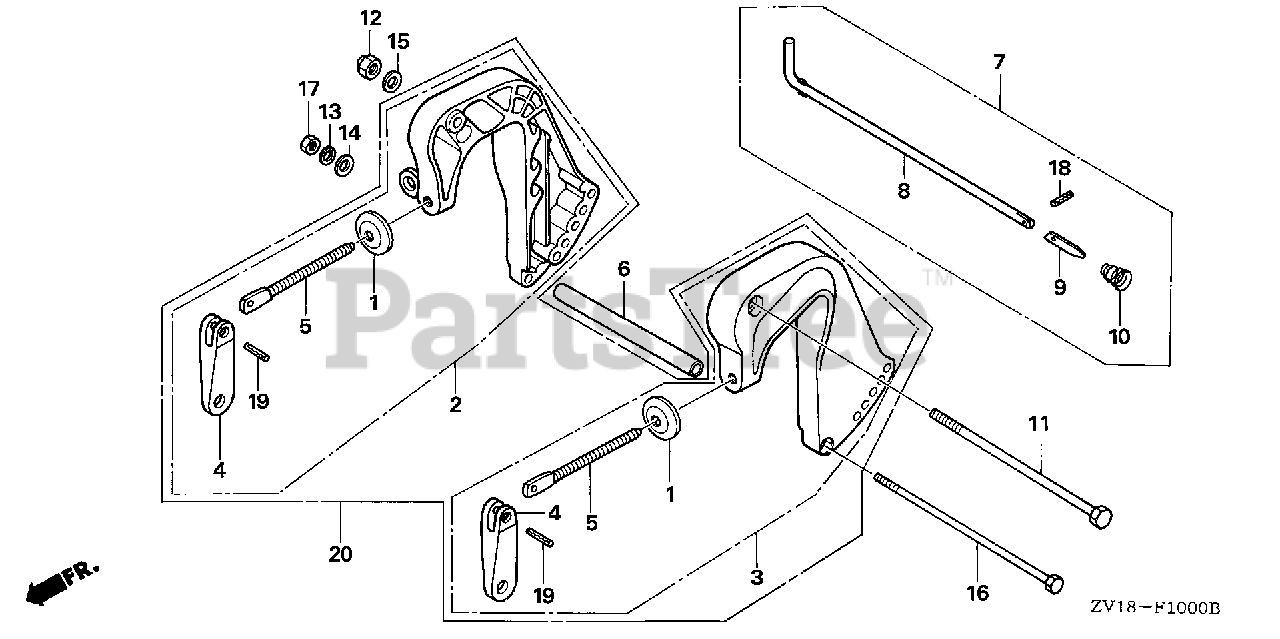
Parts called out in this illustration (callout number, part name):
1	PLATE, PUSH
2	BRACKET, R. STERN *NH282MU* (OYSTER SILVER METALLIC-U)
3	BRACKET, L. STERN *NH282MU* (OYSTER SILVER METALLIC-U)
4	GRIP, CLAMP
5	SCREW, CLAMP
6	COLLAR, DISTANCE (6MM)
7	ROD, ADJUSTING
8	ROD, ADJUSTING
9	STOPPER, ROD
10	SPRING, ROD ADJUSTING
11	BOLT, HEX. (8X130)
12	NUT, SELF-LOCK (8MM)
13	WASHER, SPRING (6MM)
14	WASHER, PLAIN (6MM) Use from Frame SN 4800713.
15	WASHER (8MM)
16	BOLT, HEX. (6X140)
17	NUT, HEX. (6MM)
18	PIN, SPRING (2X6)
19	RIVET (4X22.6)
20	BRACKET KIT, STERN *NH282MU* (OYSTER SILVER METALLIC-U) (NOT AVAILABLE)
20	BRACKET KIT, STERN *NH282MU* (OYSTER SILVER METALLIC-U)
